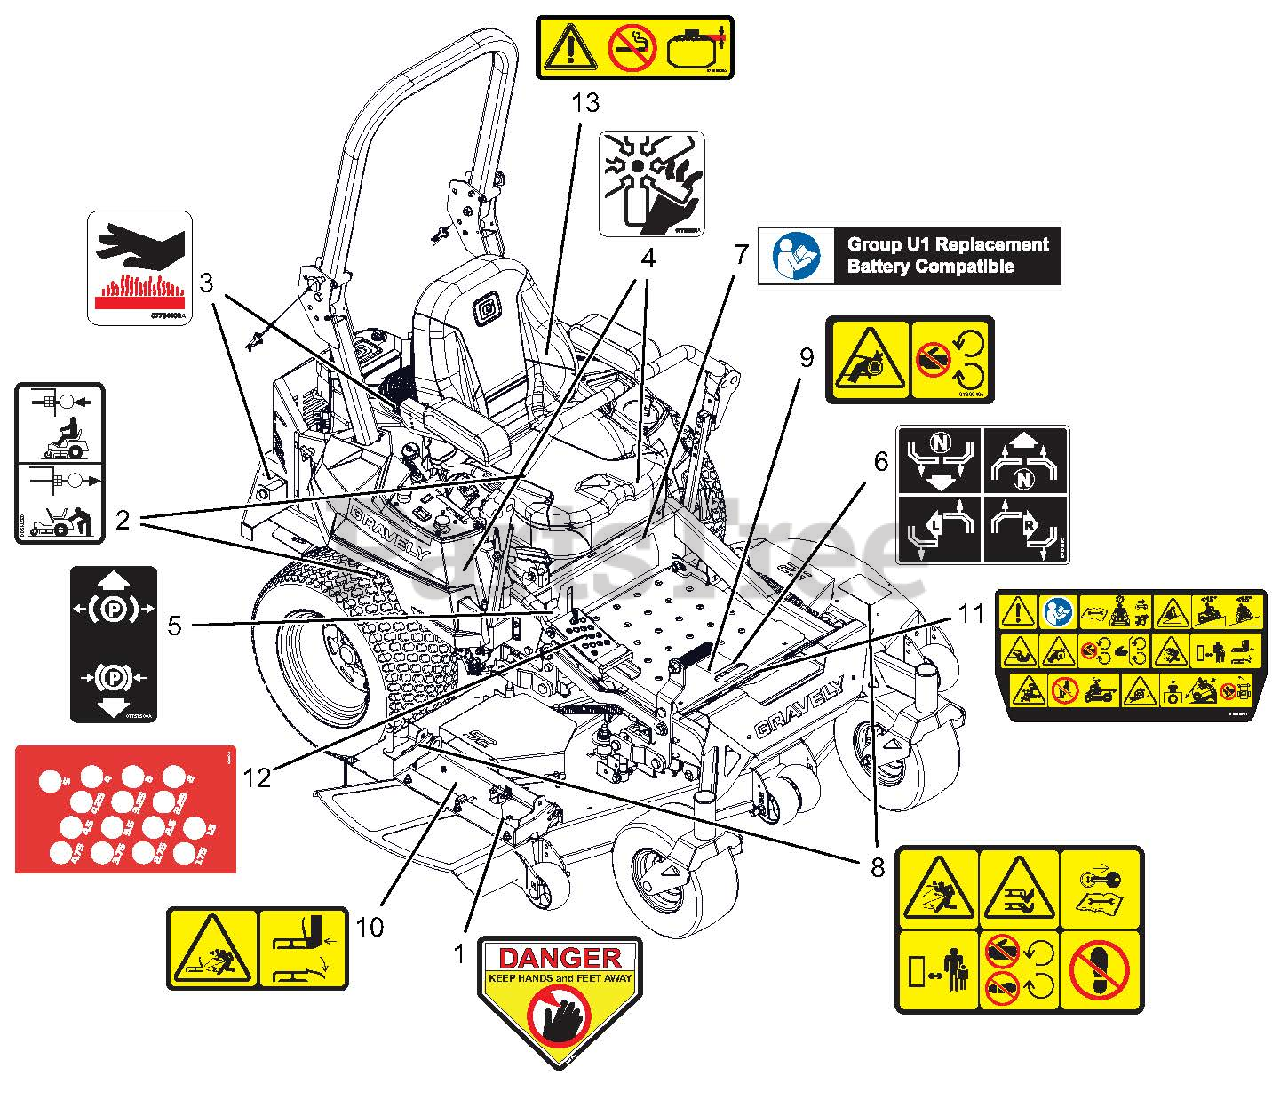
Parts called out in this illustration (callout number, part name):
1	DECAL, DANGER
2	DECAL, TRANSMISSION DISCONNECT
3	DECAL, HOT SURFACE
4	DECAL, DANGER FAN
5	DECAL, PARKING BRAKE LEVER
6	DECAL, INSTRUCTIONAL-STEERING
7	DECAL, U1 BATTERY REPLACEMENT
8	DECAL, SAFETY - MOWER DECK
9	DECAL, SAFETY - GUARDING
10	DECAL, SAFETY - DECK GUARDING
11	DECAL, MAIN SAFETY
12	DECAL - HOC
13	DECAL, FUEL WARNING
